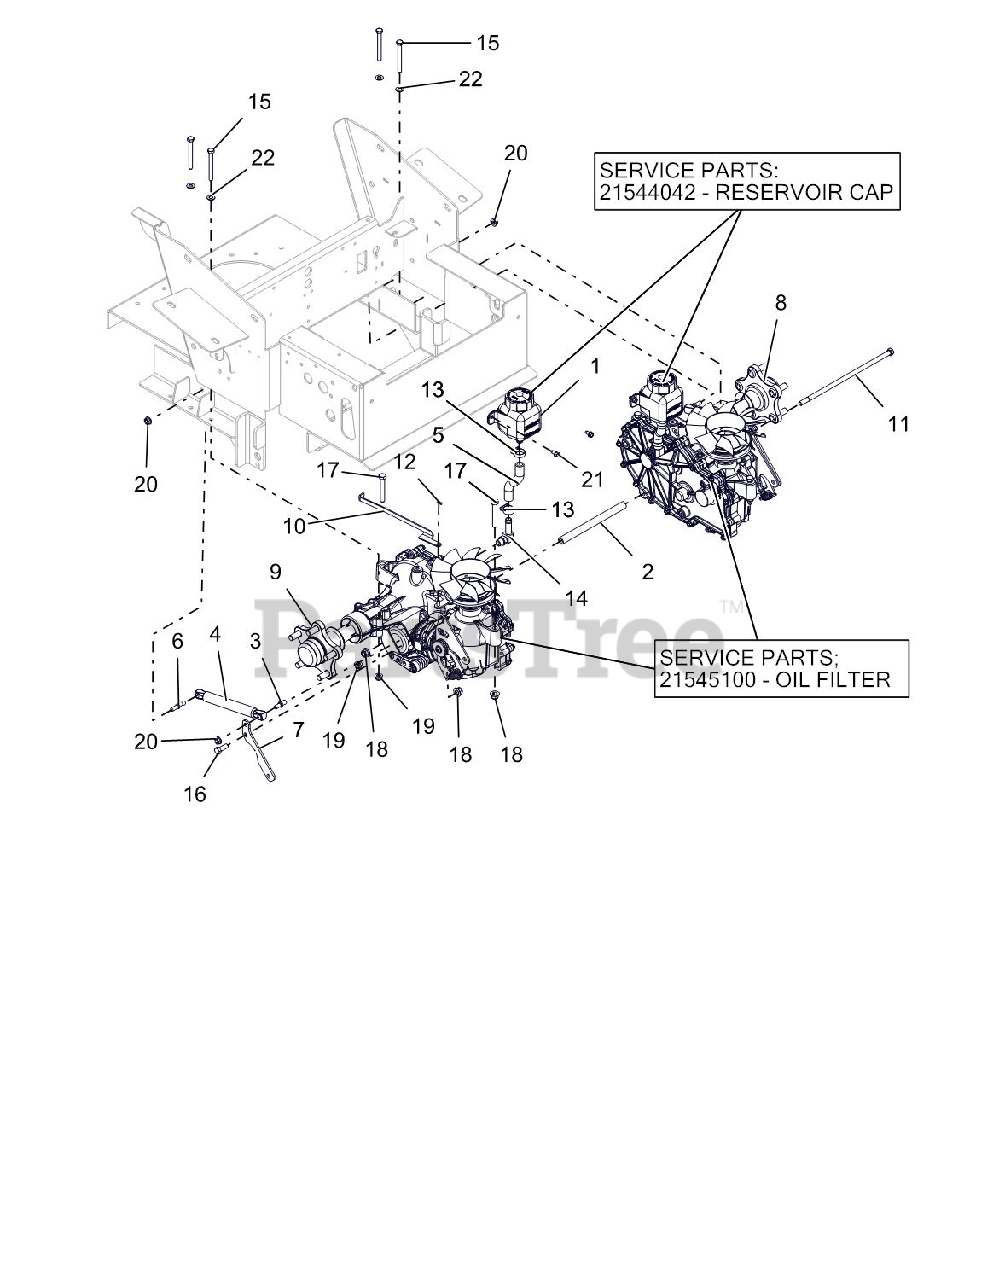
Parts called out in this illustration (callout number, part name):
1	RESERVOIR CAP
1	TANK, EXPANSION ZT2800
2	SPACER, .406 ID X .630 OD X 7.724
3	STUD-BALL
4	DAMPER,
5	HOSE, PT100 HYDRO OVERFLOW
6	STUD, BALL THREADED
7	TRANSMISSION DAMPER MTG PLATE - BLK
8	TRANSAXLE, ZT3400, LH
8	OIL FILTER
9	TRANSAXLE, ZT3400, RH
10	BRKT, DUMP VALVE
11	BLT, HEX .38-16X11.00 GR5 YWZC
12	PIN-HAIR INT .06X.18X.77
13	CLAMP, .88 DIA HOSE
14	FITTING, HYD (90 DEG)
15	BOLT, HEX 0.313-18X3 GR5
16	BOLT, HEX 0.375-16X1 GR5
17	BOLT, HEX 0.375-16X2.5 GR5
18	NUT-LK-NYL-FLG .38-16 YWZC
19	NUT-LK-NYL-FLG .31-18 YWZC
20	NUT, LK-TOP-FLG .312-18 YWZC
21	SCR-TAP .25-20X.50 HWH TR YWZ
22	WSHR-FL-STL.344X.688X.065YWZC
